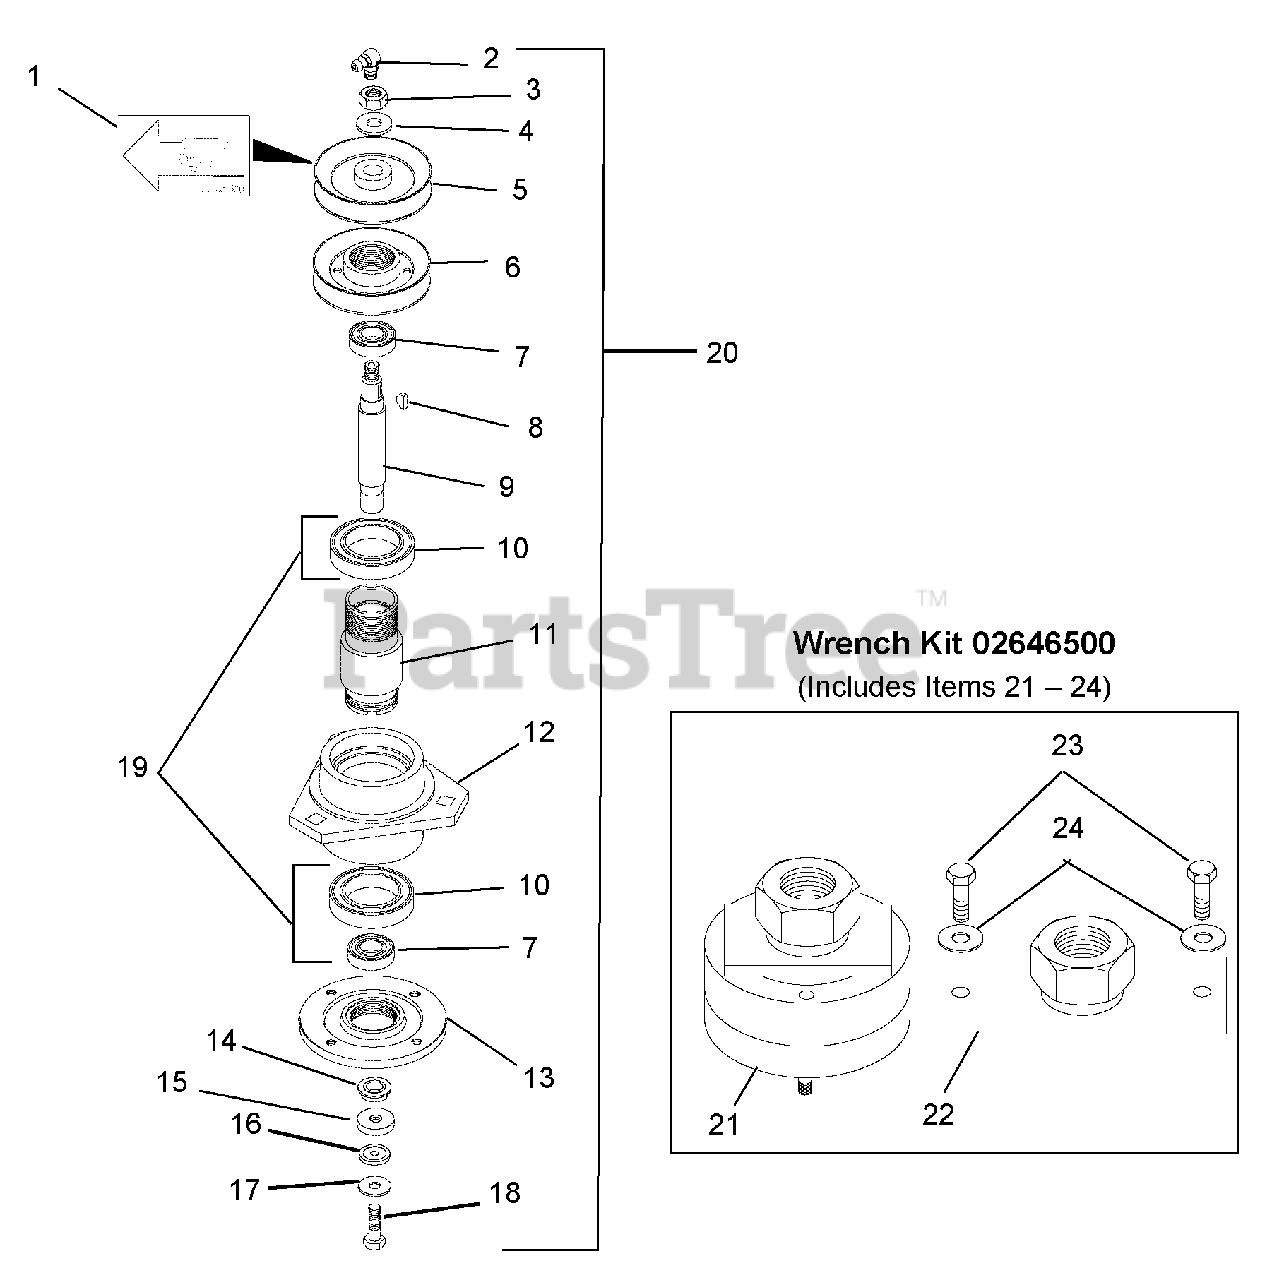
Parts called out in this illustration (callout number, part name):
1	Decal, Grease 25 Hours
2	Grease Fitting
3	Nut, Lock .625-11"
4	Washer, Washer .625"
5	Sheave, Upper 5.50 EOD
6	Sheave, Lower
7	Bearing, Inner Shaft 6205LCC4/2AQ12
8	Woodruff Key #606
9	Shaft, Inner
10	Bearing, Outer Shaft 6012-2RS C4
11	Shaft, Outer
12	Hub, Machined Spindle
13	Carrier, Blade
14	Bushing, Blade
15	Washer, Shaft
16	Washer, Blade Reinforcement
17	Washer, Heavy Duty
18	Cap Screw, Hex Head .50-20 UNF x 1.75"
19	Bearing Kit (Includes Items 7 and 10)
20	Spindle Assembly, Mulching (Includes Items 1 – 18)
21	Sheave Wrench Assembly
22	Weldment, Wrench
23	Cap Screw, Hex Head .375-16 x 1.75"
24	Washer, Flat .375"
